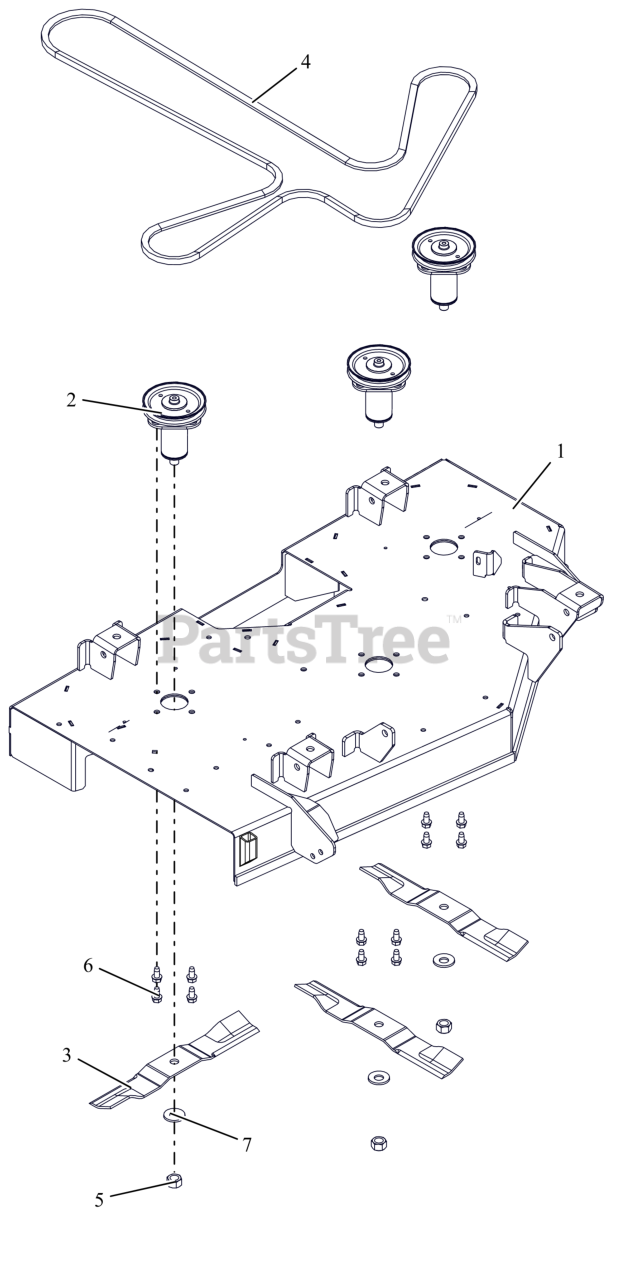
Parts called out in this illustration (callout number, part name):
1	WLDMT, DECK 42" (ORANGE)
2	KIT, DECK SPINDLE ASM-IKON-ZTX
3	BLADE, MOWER 15.00"
4	V-BELT, 4L-WRAPPED
5	NUT-STD .625-18 ZCC
6	SCR,TAP .375-16X.75 HWH TR ZCC
7	WSHR-BLVL .669X1.535X.138
